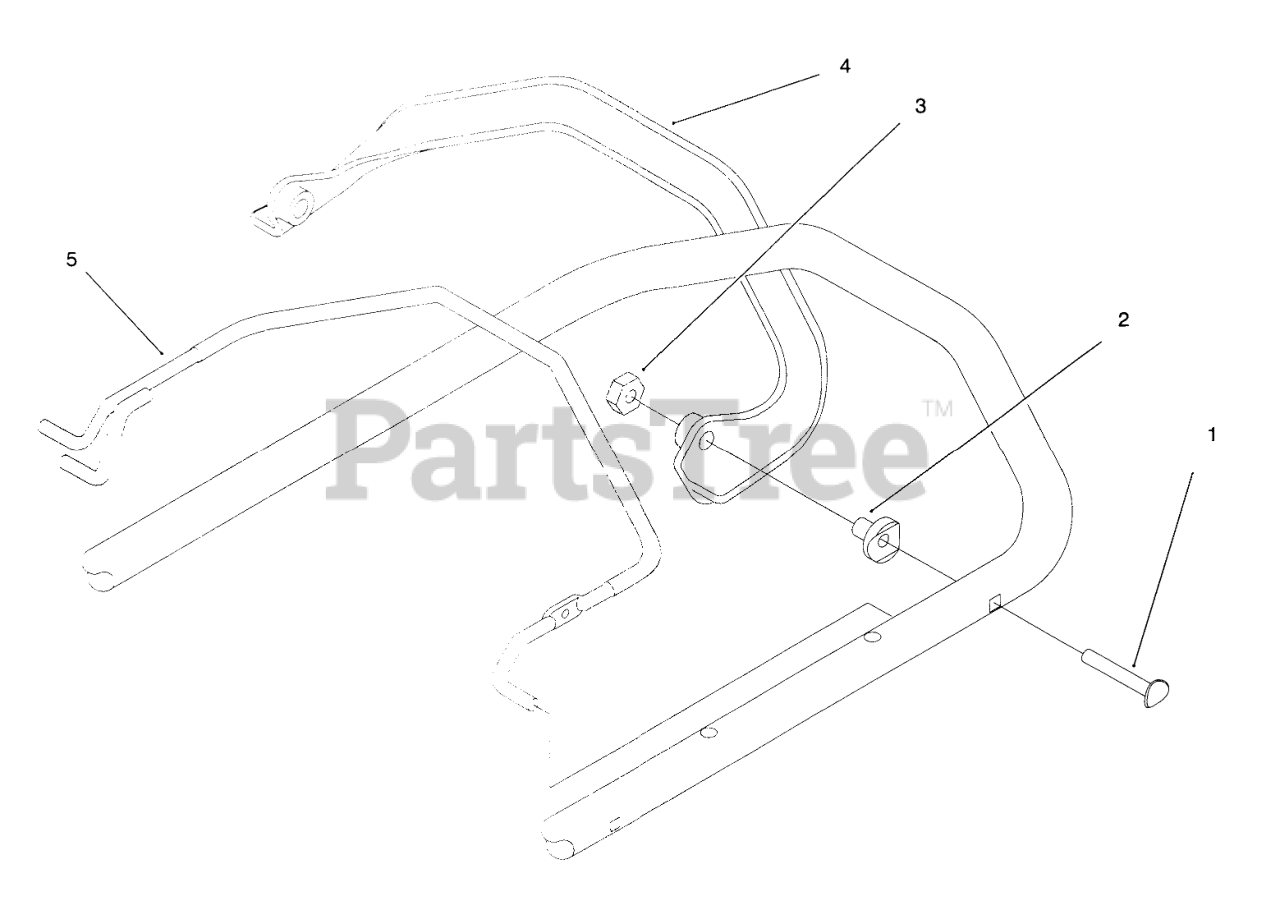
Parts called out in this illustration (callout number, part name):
1	SCREW-HANDLE
2	SPACER-SUPPORT
3	NUT-LOCK NI
4	BAIL - TRACTION
5	Bail-Brake
